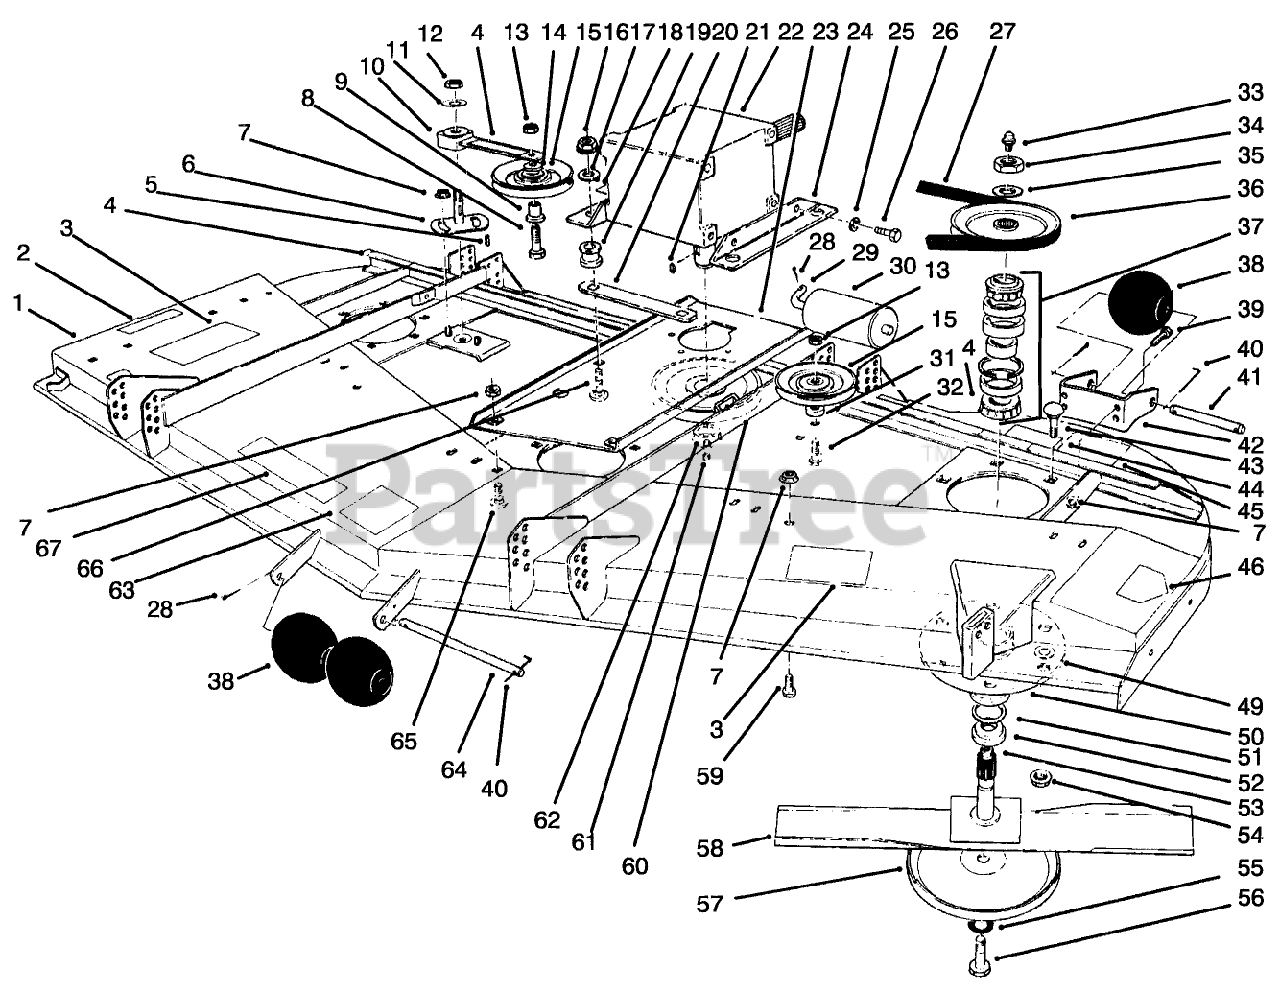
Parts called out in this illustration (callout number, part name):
1	62 DECK W/ DECALS
2	DECAL-DANGER
3	DECAL-DANGER, THROWN OBJECT
4	DECAL-DANGER
5	KEY-SQUARE
6	PLATE-IDLER
7	NUT-HHF, WHIZ
8	SCREW-HH
9	BUSHING-PULLEY
11	WASHER-FLAT
12	NUT-LOCK, NI
13	NUT-HEX
14	WASHER-FLAT
15	PULLEY-IDLER
16	NUT-LOCK, SIDE
17	WASHER
19	MOUNT
21	KEY-WOODRUFF
25	WASHER-LOCK
26	SCREW-HH
27	V-BELT
28	PIN-COTTER
29	SHAFT-ROLLER, REAR
30	ROLLER-DECK
31	SPACER
32	SCREW-HH
33	FITTING-GREASE
34	NUT-HEX
35	WASHER
36	PULLEY AND HUB ASM
37	BEARING ASM
38	ROLLER
39	SCREW-HH
40	PIN-SPECIAL
41	SHAFT-ROLLER
43	SCREW-CARR
44	DECAL-TORQUE
45	DECAL-WARNING
46	DECAL-DANGER
49	WASHER-FLAT
50	HOUSING-SPINDLE
51	SEAL-OIL
52	SPACER
53	SHAFT
54	NUT-HF
55	WASHER
56	SCREW-BLADE
57	CUP-SCALP, ANTI
59	SCREW-HH
60	GEARBOX PULLEY ASM
61	SCREW-SET, HSH
62	BUSHING-LOCK, TAPER
63	DECAL
64	SHAFT-ROLLER
65	SCREW-CARR
66	SCREW-CARR
